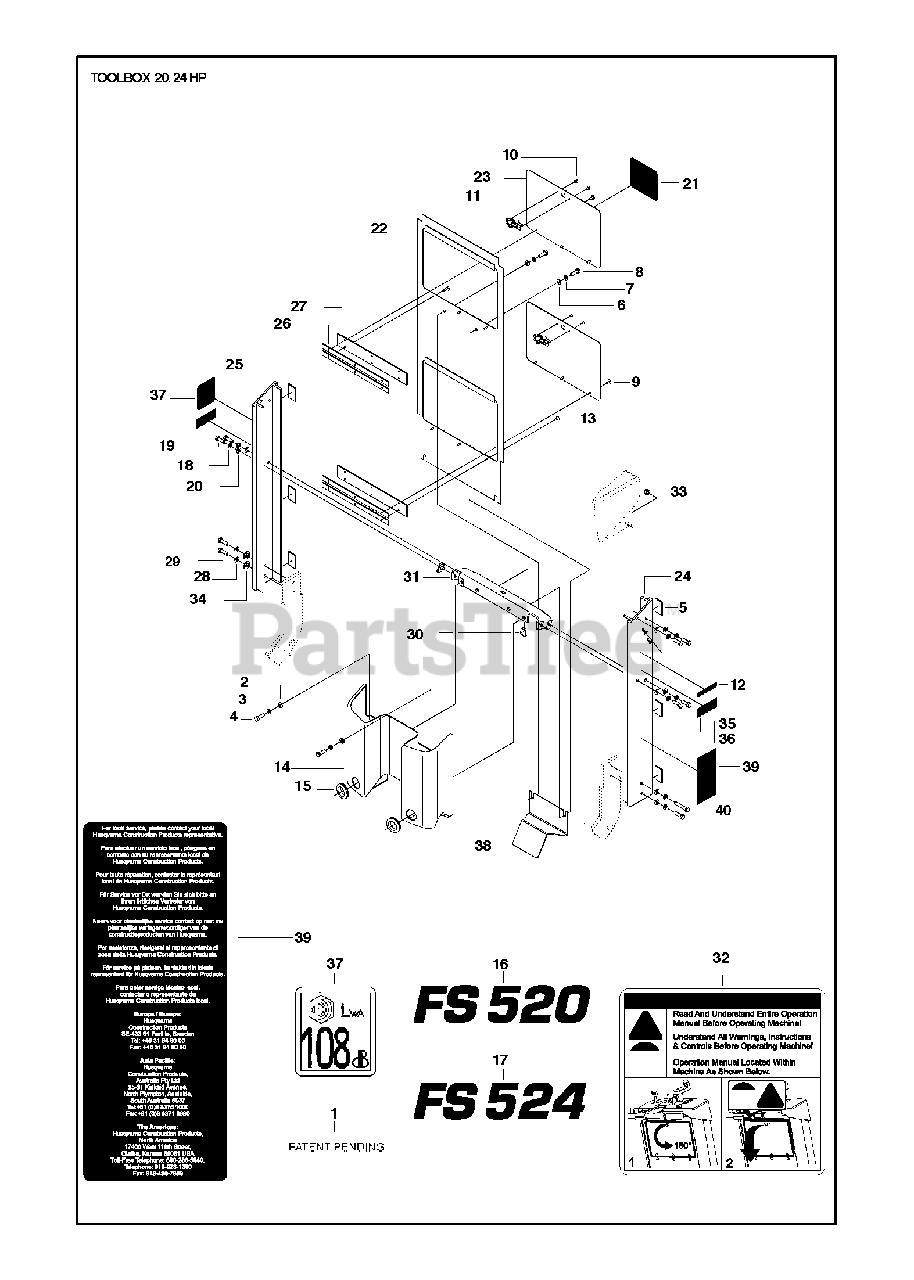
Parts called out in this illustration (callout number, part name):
2	WASHER
3	SPRING WASHER
6	WASHER
7	SPRING WASHER
18	SPRING WASHER
20	WASHER
28	SPRING WASHER
33	HEXAGON LOCKING NUT
34	WASHER
40	SCREW EHHM
